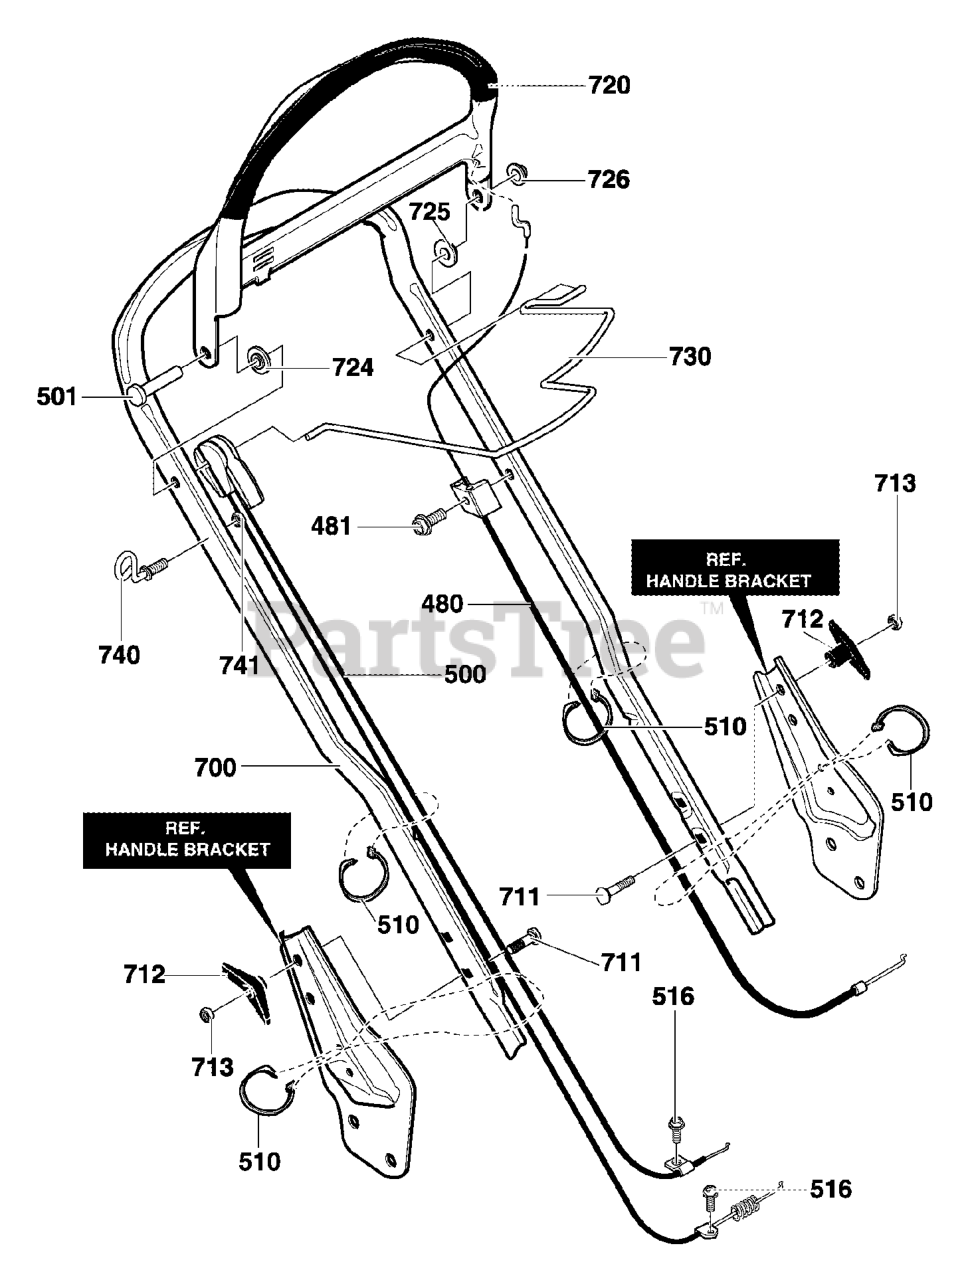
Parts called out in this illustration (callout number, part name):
480	CABLE,STOP
481	SCREW, 10-16X.75 S
500	CABLE, DRIVE
501	SCREW,#10-16X1.38
510	TIE, CABLE BLACK NYLON 5.62L
516	SCREW,10-16X.50HWASEMTAP
700	HANDLE
711	BOLT, 5/16-18X2.00
712	KNOB, T W/516/18 NUT
713	NUT, 5/16-18 REGHEX
720	LEVER, STOP FLAT
726	CAP, RETAINER
730	LEVER, DRIVE WIRE
740	GUIDE, ROPE 1/4-20
741	NUT, 1/4-20
